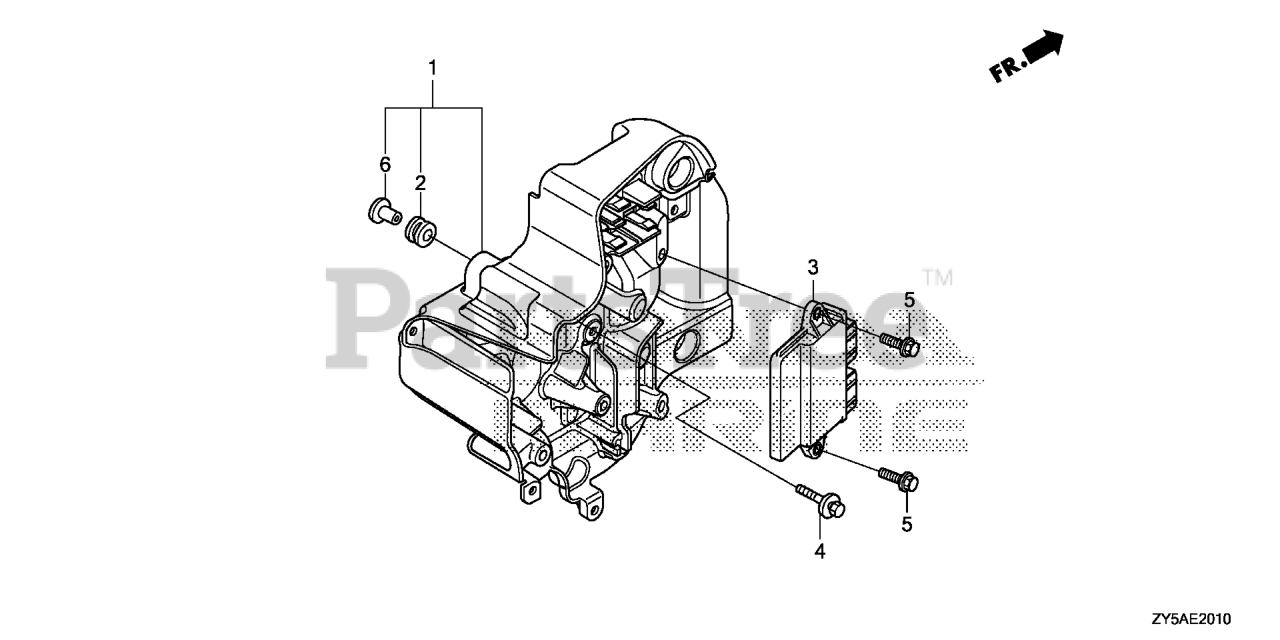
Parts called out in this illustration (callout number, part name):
1	CASE ASSY.
2	GROMMET, ELECTRONIC PARTS CASE
3	CONTROL UNIT, ELECTRONIC
4	BOLT-WASHER (6X27) (CT200)
4	BOLT-WASHER (6X27)
5	BOLT, FLANGE (6X20)
6	COLR, CDI UNIT CASE
6	COLLAR, MODULE IGNITION CONTROL CASE (CDI)
